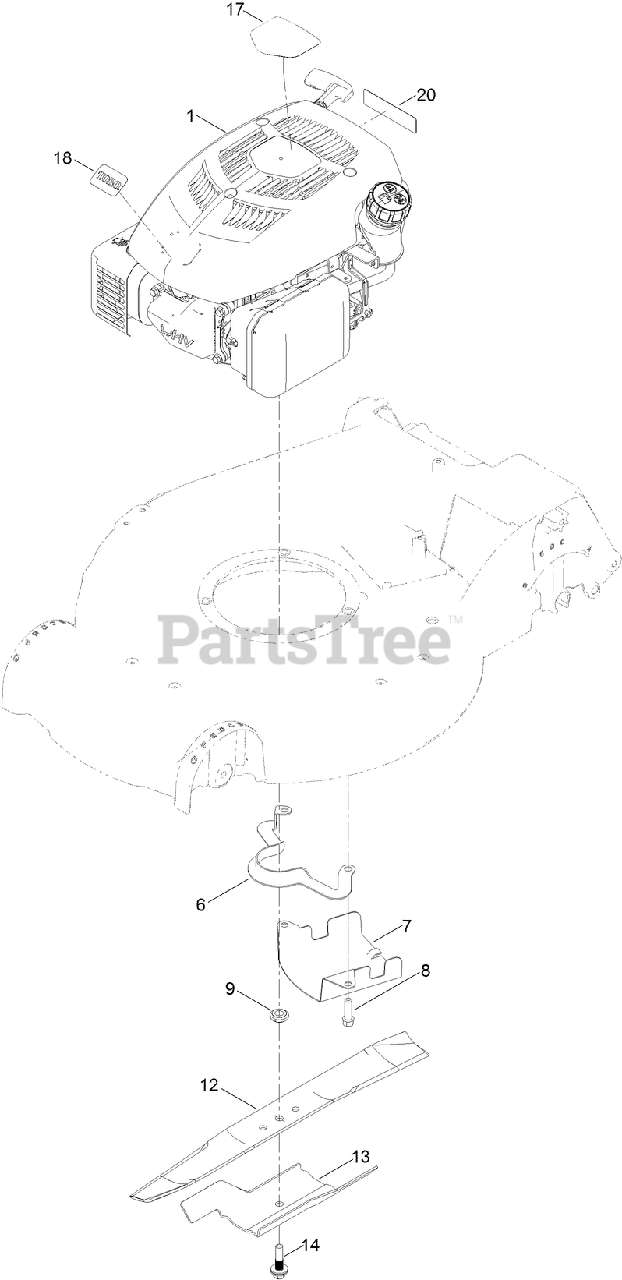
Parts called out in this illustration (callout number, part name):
1	ENGINE-1P65F-2
6	GUIDE-BELT
7	SHIELD-GRASS
8	SCREW-TAPTITE
9	Spacer-Driver
12	BLADE-21IN, RECYCLING
13	Accelerator-Blade
14	BOLT-BLADE
17	DECAL-SHROUD
20	DECAL-ARRESTER, SPARK
